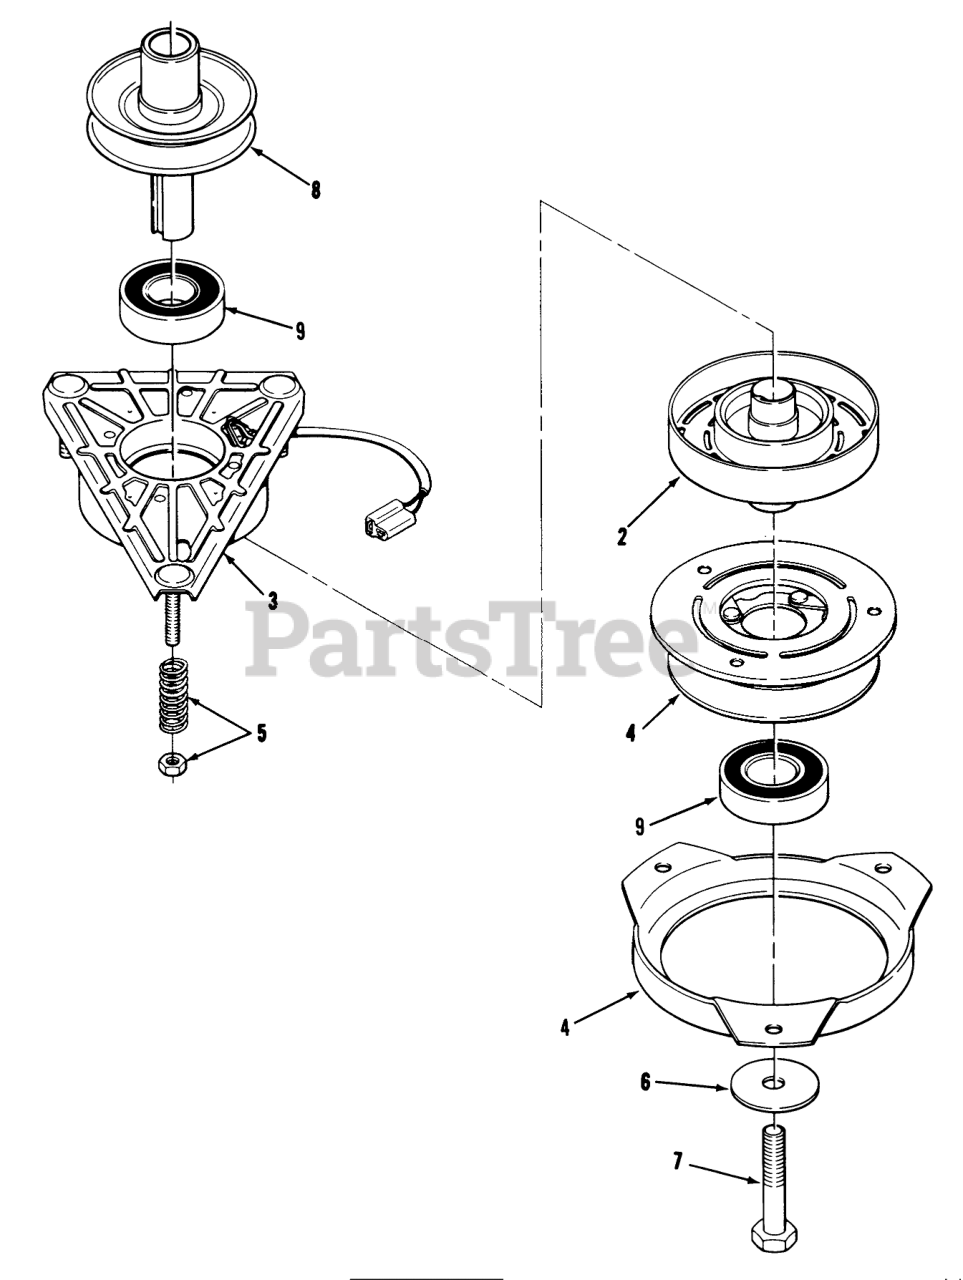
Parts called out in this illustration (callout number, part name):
1	Electric Clutch Assembly (Incl. Ref. #2-5)
2	ASS'Y-ROTOR
3	Field Assembly (Incl. Ref. #9)
4	Armature & Pulley Assy. (Incl. Ref. #9)
5	ACCESS SPRING & NUT
6	WASHER
7	Bolt
8	PULLEY-ENGINE
9	BEARING-ELEC CLUTCH
